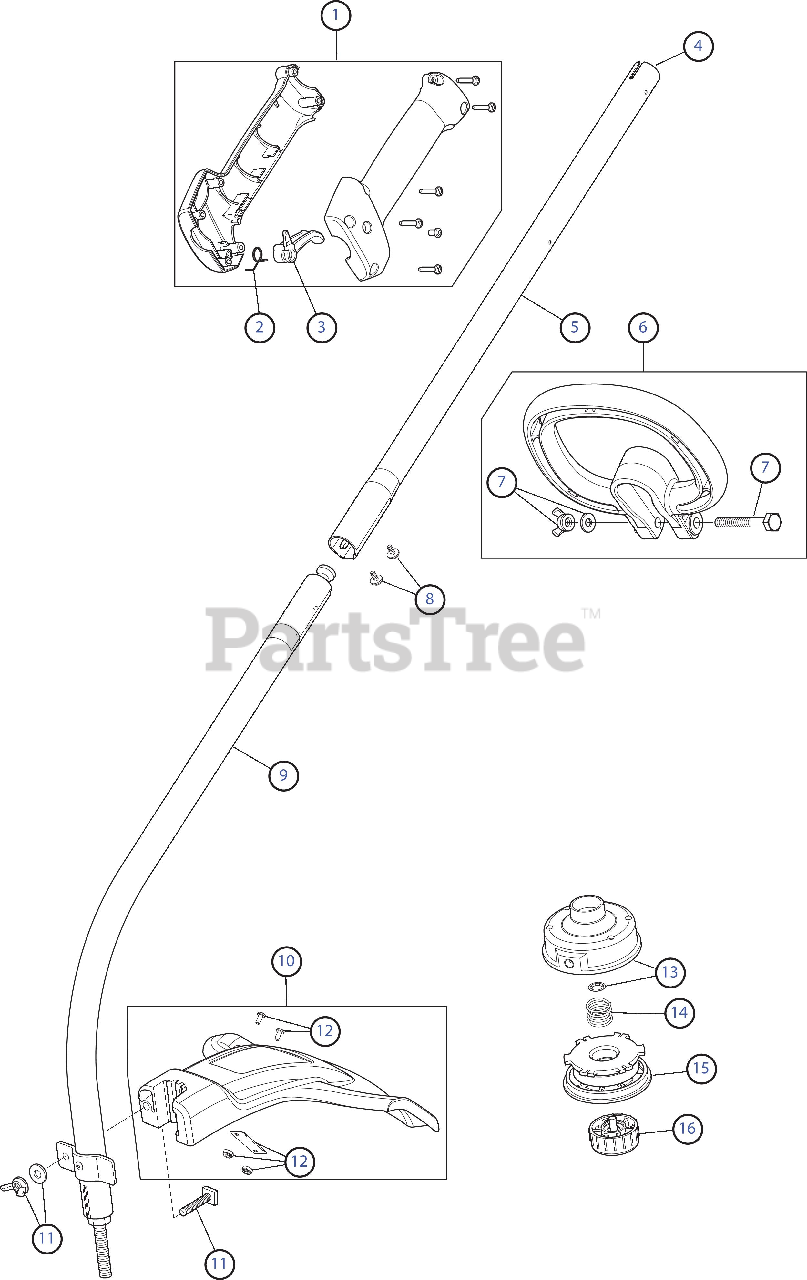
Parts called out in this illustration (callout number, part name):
1	Throttle Housing Assembly
2	Throttle Trigger Spring
3	Throttle Trigger
4	Flexible Drive Shaft
5	Upper Shaft Housing Assembly
6	D-Handle
7	D-Handle Hardware
9	Lower Shaft Housing Assembly
10	Shield Assembly
11	Shield Mounting Hardware
12	Blade Assembly
13	Outer Spool Assembly
15	Inner Reel
16	Bump Head Knob Assembly
